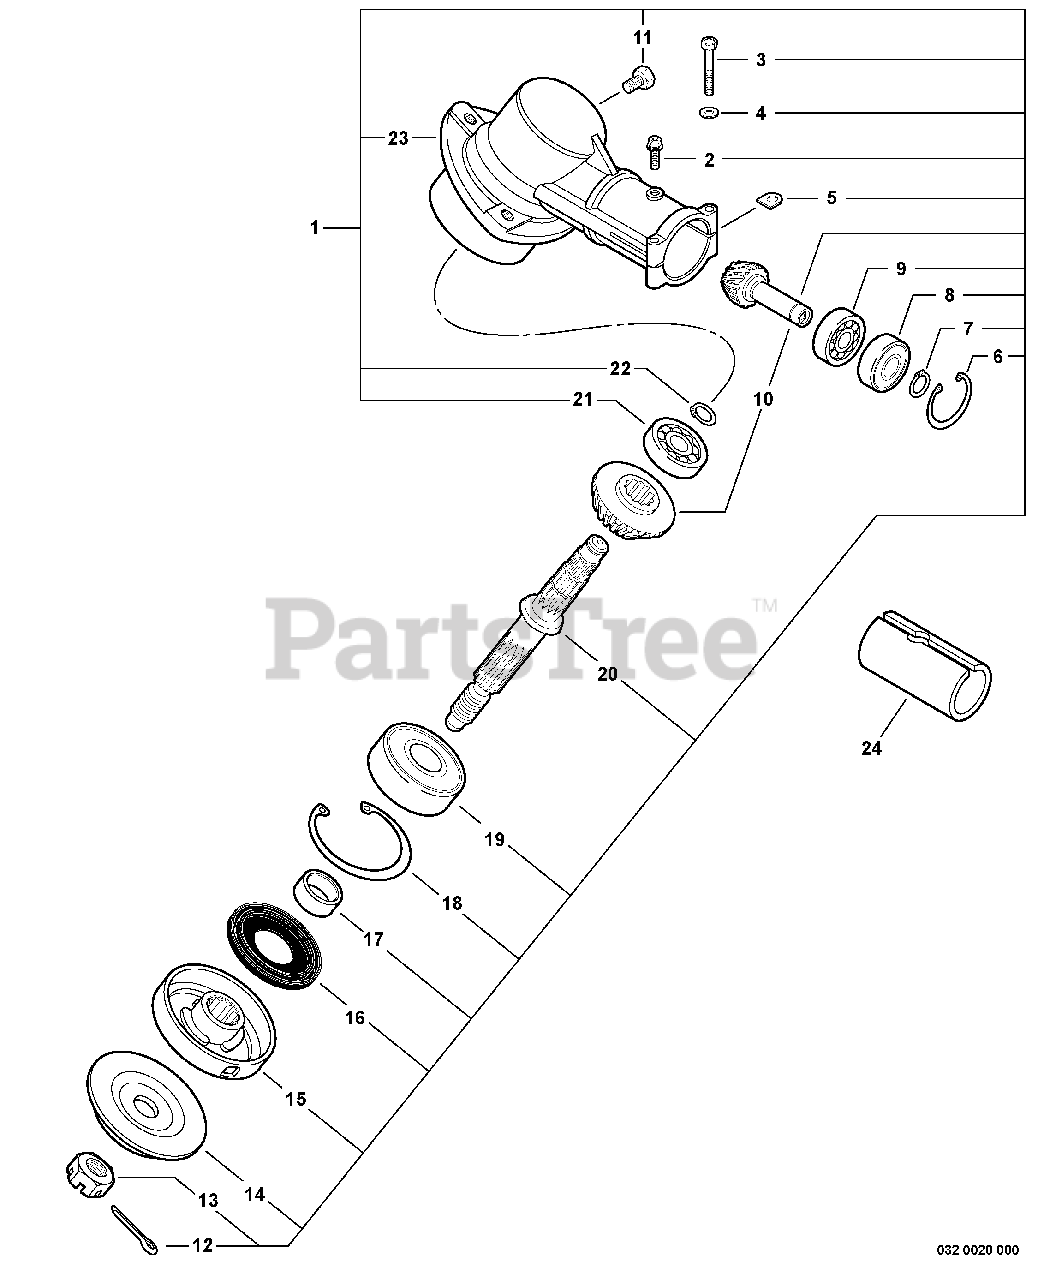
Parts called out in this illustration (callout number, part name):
1	GEAR CASE ASSY
2	SCREW - 5X14
3	BOLT - 5X30
4	WASHER - 5
6	RING, RETAINING - 28
7	RING, RETAINING - 12
8	BEARING, BALL - 6001
9	BEARING, BALL - 6001
10	GEAR SET
11	BOLT - 8X8
12	PIN, SPLIT - 2X22
13	LOCKNUT - LEFT HAND
14	ADAPTOR, BLADE - LOWER
15	ADAPTOR, BLADE - UPPER
16	SEAL, OIL
18	RING, RETAINING - 32
19	BEARING, BALL - 6201
20	GEAR - SHAFT
21	BEARING, BALL - 6000
22	RING, RETAINING - 12
23	CASE, GEAR
